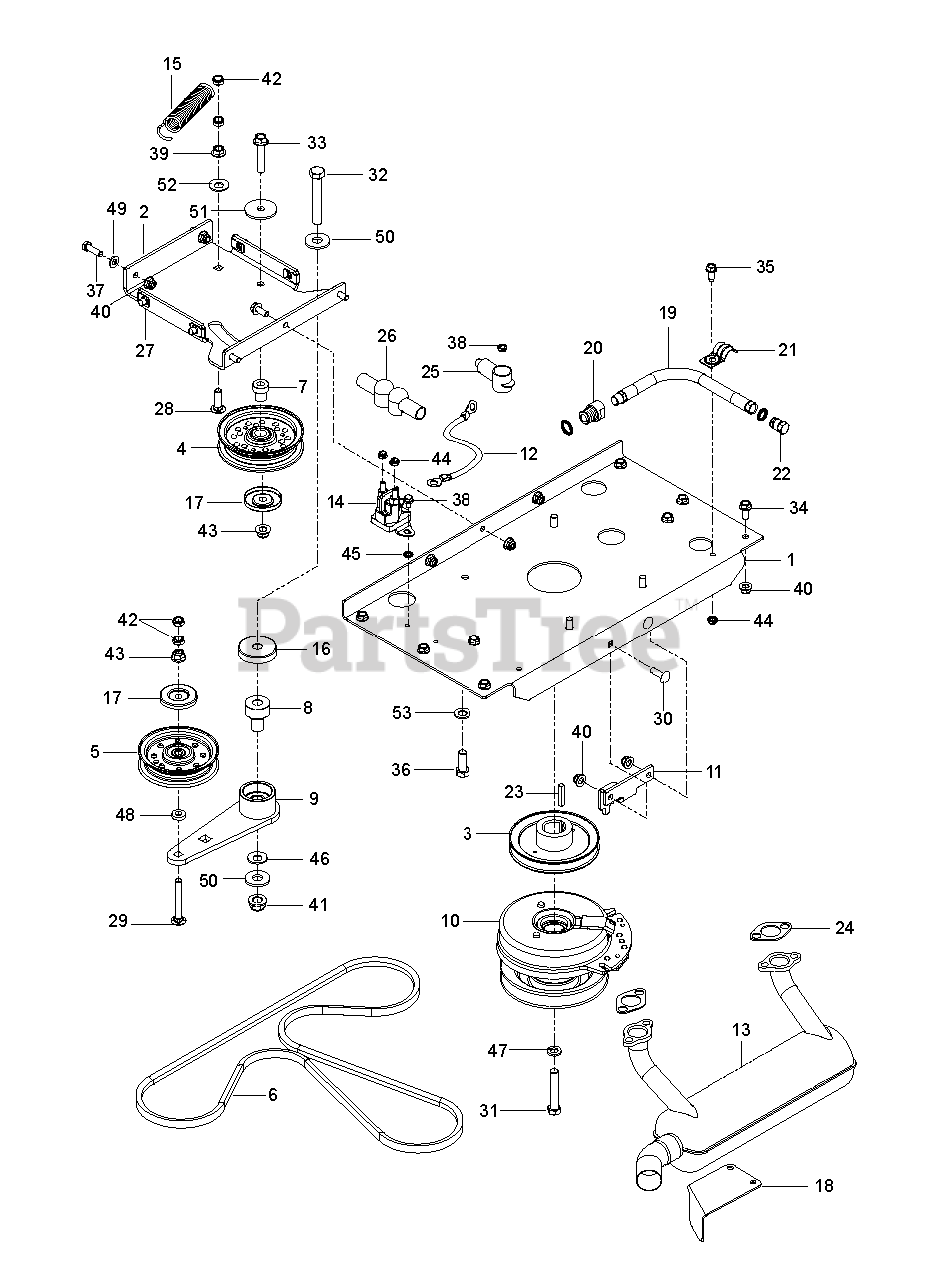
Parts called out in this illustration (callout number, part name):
1	PLATE.PNT.ENGINE.E-DIP
2	PLATE, IDLER, BLK
3	PULLEY, V, 1.125 BORE
4	IDLER PULLEY
5	PULLEY.IDLER.FLAT.46.PR.DR.
6	BELT, HYDRO, 3400
7	PIVOT, IDLER
8	PIVOT, BEARING
9	ARM, IDLER, STEEL, W/BGS
10	CLUTCH 200 FT LB
11	STOP, CLUTCH, BLACK
12	CABLE POSITIVE
13	MUFFLER.26HP.KAW.FX651V-730V
14	SOLENOID.STARTER.BRASS.PLUNGER
15	SPRING, PUMP
16	SHIELD, DUST
17	DUST SHIELD
18	SHIELD MUFFLER
19	HOSE.ASSEMBLY.OIL.DRAIN
20	ADAPTER, OIL DRAIN
22	PLUG, DRAIN 3/8 NPTF
23	KEY, 1/4 SQ X 1 1/4
24	GASKET.EXHAUST.KAWASAKI
26	TERMINAL COVER
27	U-CLIP 5/16-18 NUT RETAINER
28	BOLT.3/8-14X1.25
29	RHSNB 3/8-16 X 2.75
31	CLUTCH BOLT7/16-20X2.5 GR596HR
32	HCS 1/2-13 X 3-1/4 GD 5 ZD
33	HHFS 3/8-16 X 2.0 GD 5
34	HHFS 5/16-18 X 3/4
35	HCS 1/4-20.
36	HCS 3/8-16X1.GRD.5.ZD
37	HCS 5/16C X 1
38	RP_SCREW.1/4-20X3/8
39	NUT 3/8C WHIZ
40	5/16-18 NYLOC FLANGE NUT
41	NUT, 1/2-13 HEX FLG NYLOC ZD
42	NUT HEX 3/8-16 NYLON, THIN
43	NUT 3/8-16 HEX FLG NYLOC ZD
44	JAM NUT 1/4C (2 2 PW01)
45	WASHER 1/4 INT TOOTH
46	CONTACT BELLSPR 1/2
47	WASHER 7/16 LOCK
48	WASHER 3/8 X 3/4 X .187 TK
49	WASHER
50	WASHER.9/16 X 1 3/8 X 12 GA.
51	WASHER, 3/8 SPEC
52	RP WASHER 3/8 FLAT
53	SLW 3/8 STD
